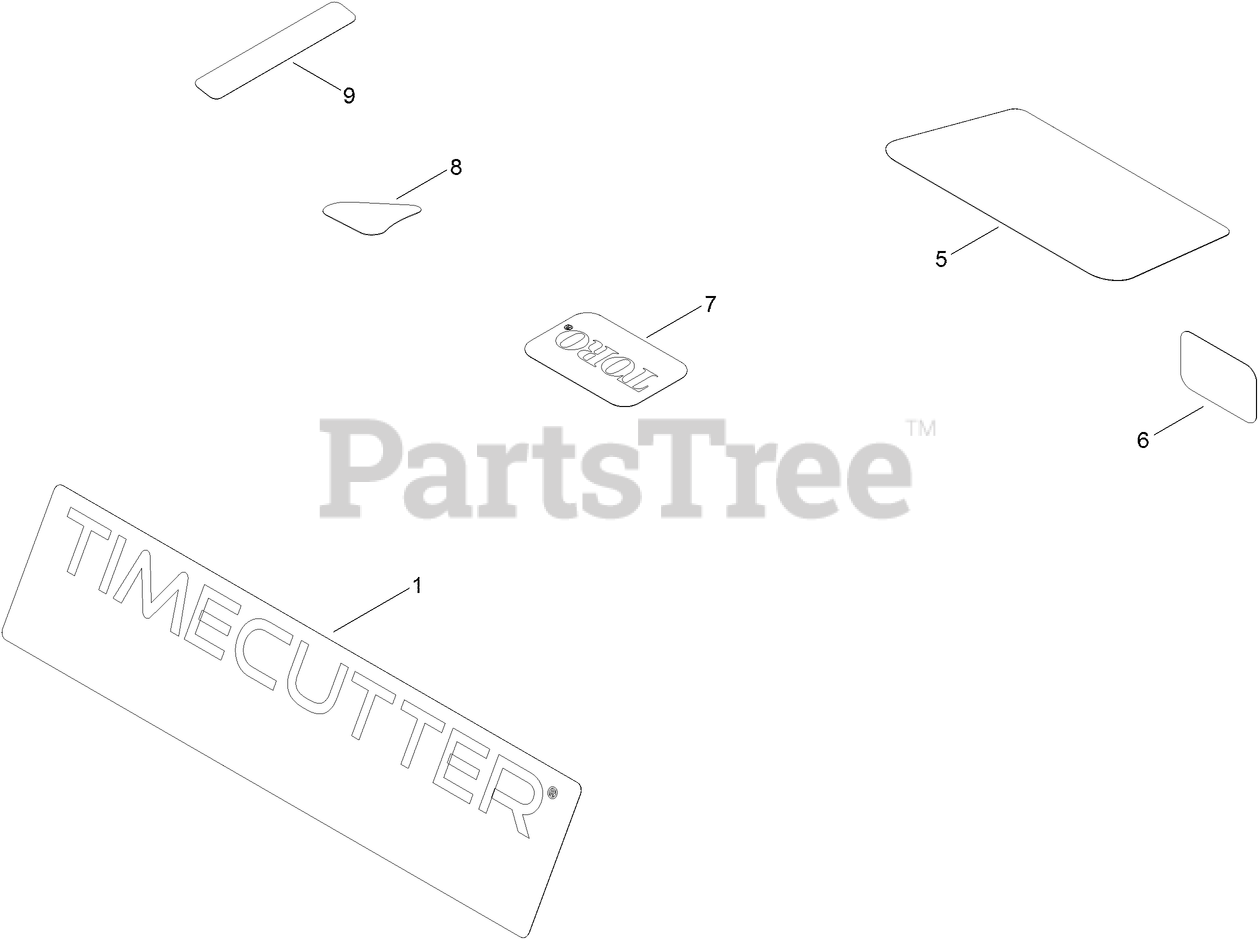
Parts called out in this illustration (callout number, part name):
1	DECAL-TIMECUTTER
5	DECAL-ENGINE
6	PLACARD-INTAKE
8	DECAL-DRAIN, OIL
9	DECAL-SHUTDOWN
